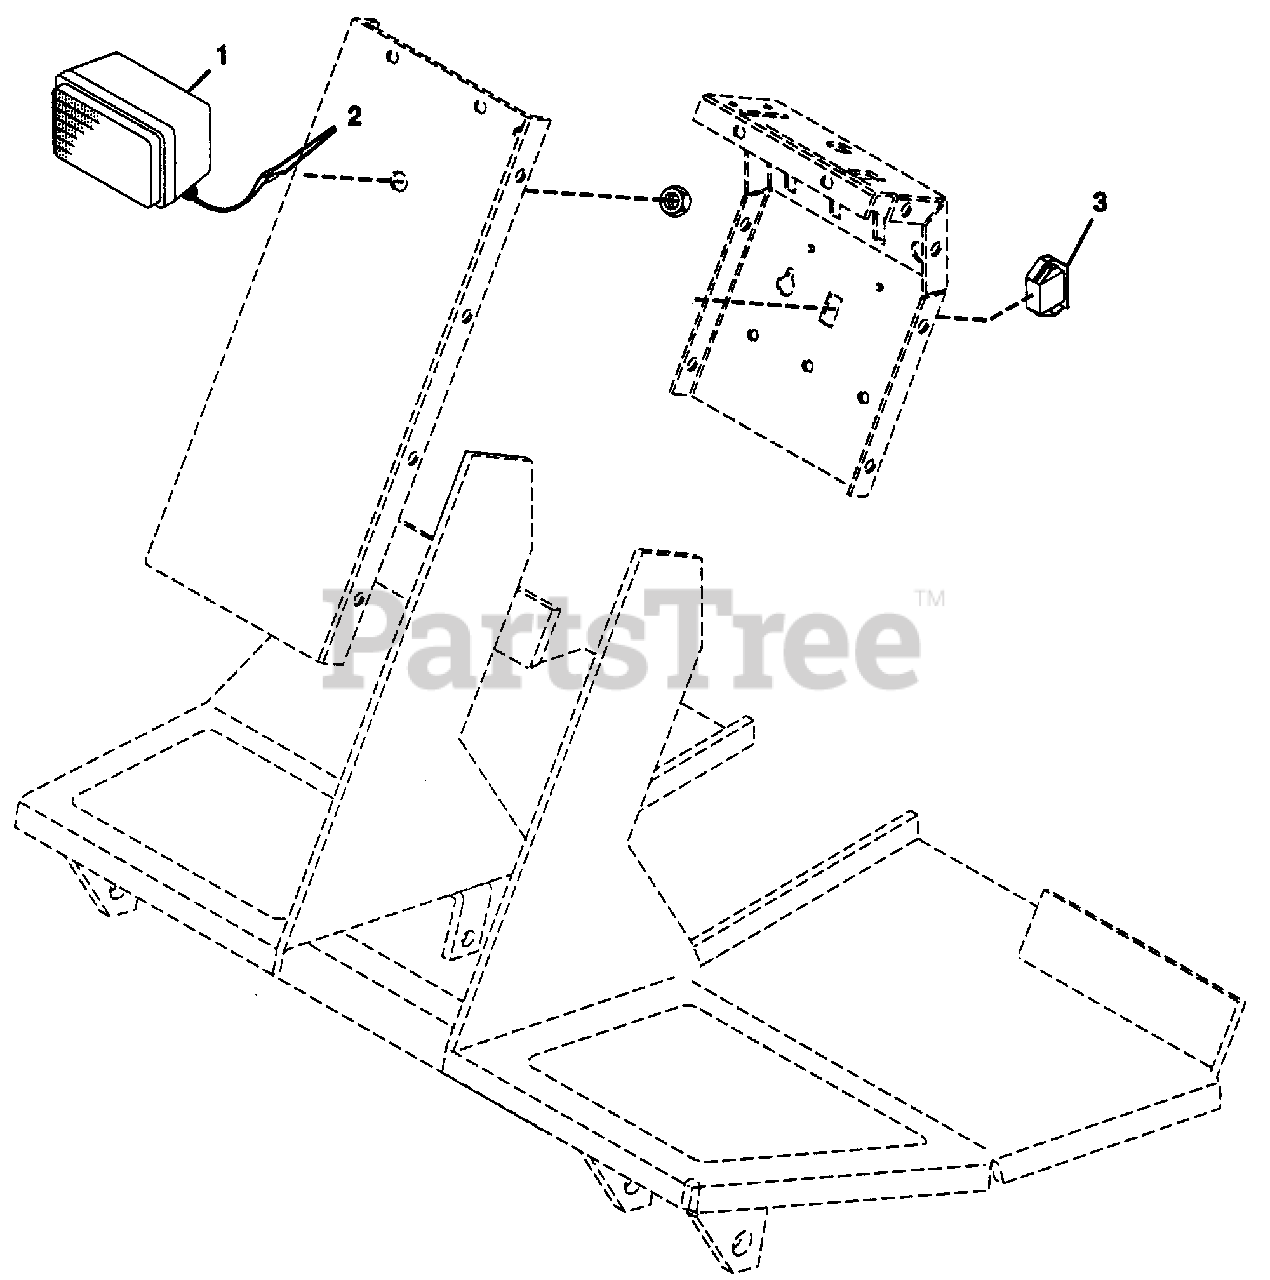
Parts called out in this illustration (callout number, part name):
1	Headlamp, 3x5 Halogen
2	Terminal, Male
3	Switch, Light
